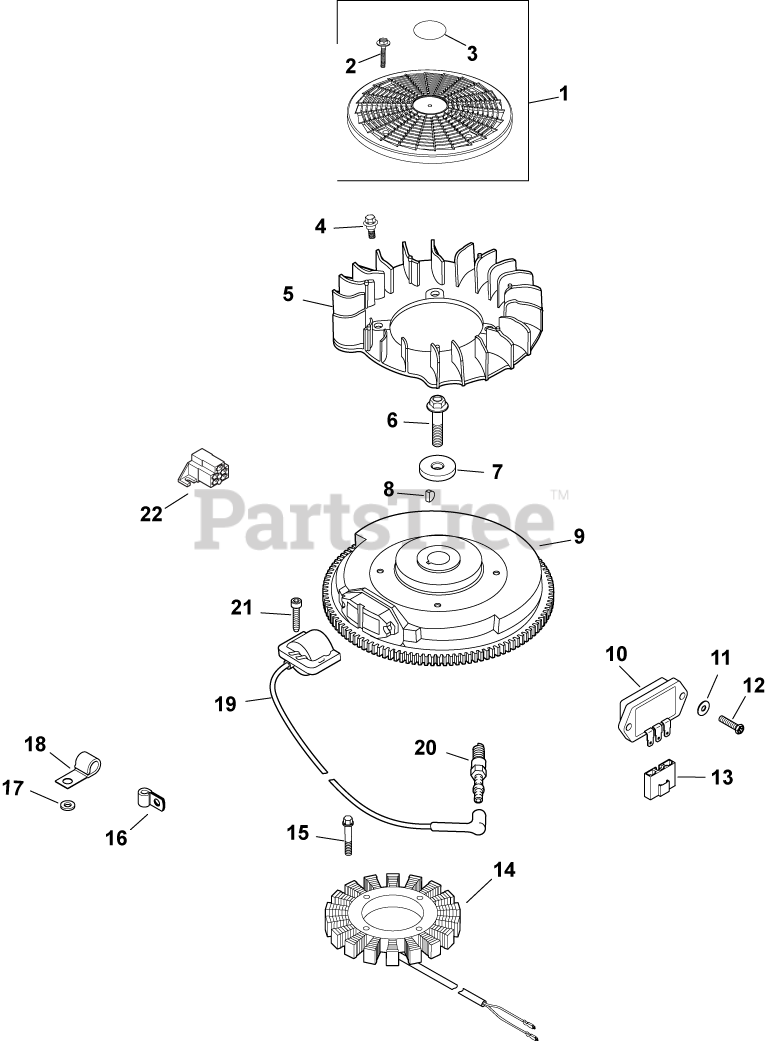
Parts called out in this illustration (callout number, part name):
1	KIT, GRASS SCREEN
2	SCREW, FLG SEMS M4X.7X25
3	DECAL, GRASS SCREEN USE 24 113 499-S
4	BOLT, SHOULDER
6	SCREW, FLG M10X1.5X45 - (#25086361S)
7	WASHER, FLAT 13/32"
8	KEY, 3/16" X 5/8"
9	FLYWHEEL, PAINTED-USE 24 025 55-S
10	REG/RECTIFIER (20/25 AMP)-USE 25 403 20-
11	WASHER, FLAT 7/32"
12	SCREW, PHL HD #11-16X7/8"
13	CONNECTOR, BODY (KM)-USE 25 155 41-S
14	KIT, 15 / 20 AMP STATOR
15	SCREW, M5X0.8X25 - (#25086402S)
16	CLIP, CABLE
17	WASHER, FLAT 1/4" (O.D. 1/2")
18	CLIP, TUBE & WIRING (KM)
19	KIT, MODULE IGNTN (CDI FIXED)
20	PLUG, SPARK (PRO SERIES)
21	SCREW, FLG THD FRM M5X.8X20-(#25086399S)
22	CONNECTOR
